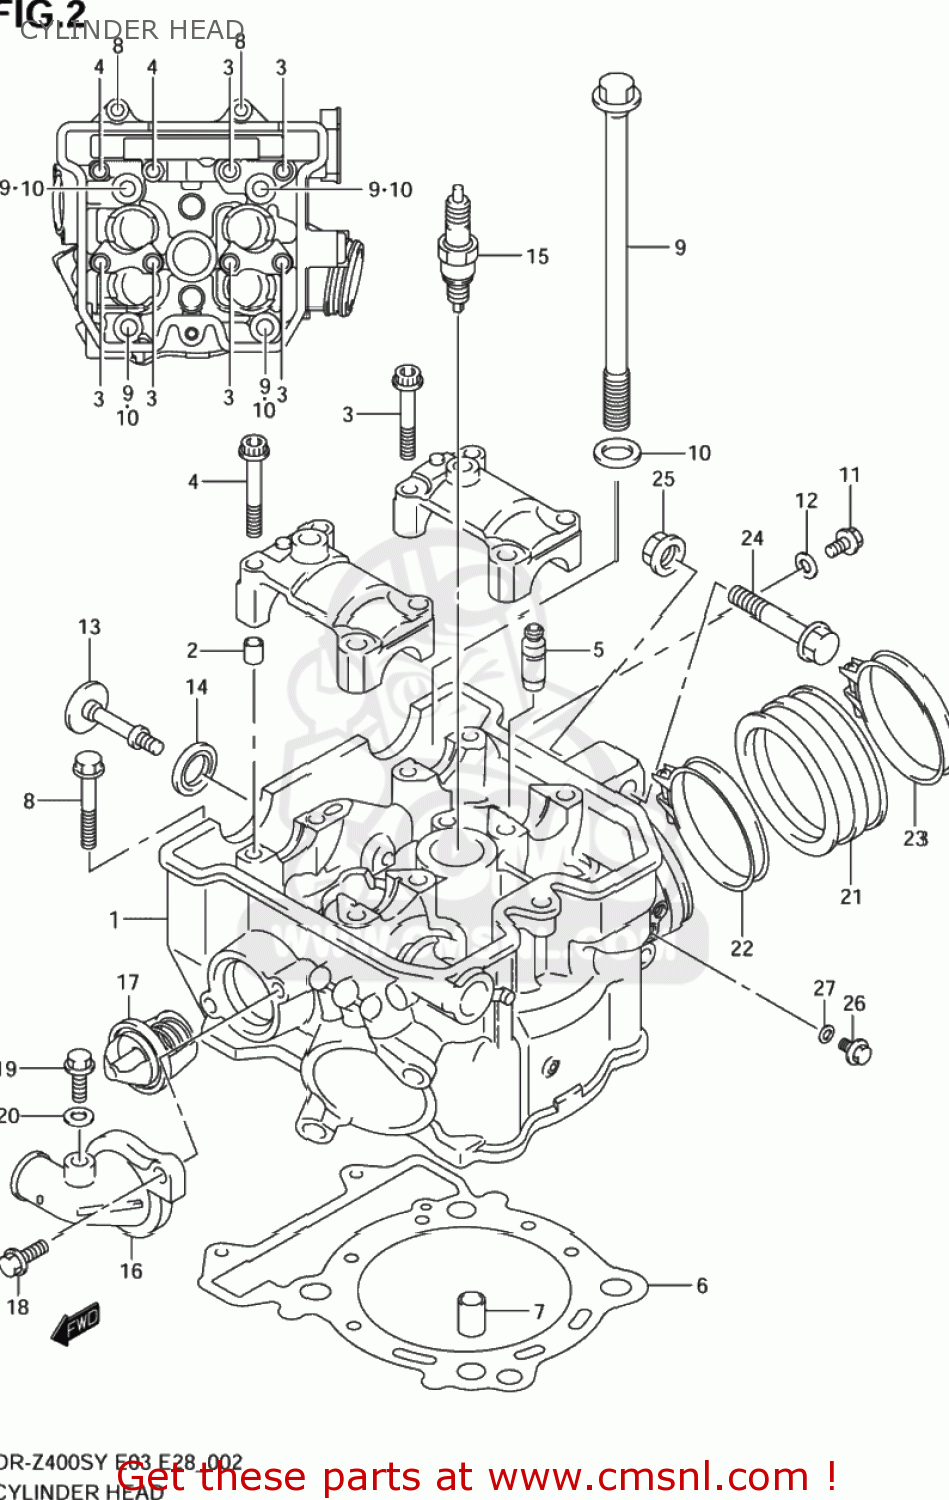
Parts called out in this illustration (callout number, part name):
1	HEAD ASSY,CYLINDER
2	PIN(6.2X8X11)
3	BOLT
5	GUIDE,VALVE
6	GASKET,CYLINDER HEAD (NAS)
7	PIN
8	BOLT(6X39)
9	BOLT(10X175)
10	WASHER(10.5X19X2)
11	BOLT
12	GASKET(5.8X13X1.2) (NAS)
13	BOLT,CYL HEAD SIDE FACE
14	WASHER,HEAD COVER
15	PLUG,SPARK(CR8E)
16	COVER,THERMOSTAT
17	THERMOSTAT,WATER
18	BOLT
19	UNION BOLT,AIR VENT
20	GASKET(6.4X11.5X0.8) (NAS)
21	PIPE,INTAKE
22	CLAMP
23	CLAMP
24	BOLT(10X50)
25	NUT
26	BOLT
27	GASKET(8.2X14X1) (NAS)
